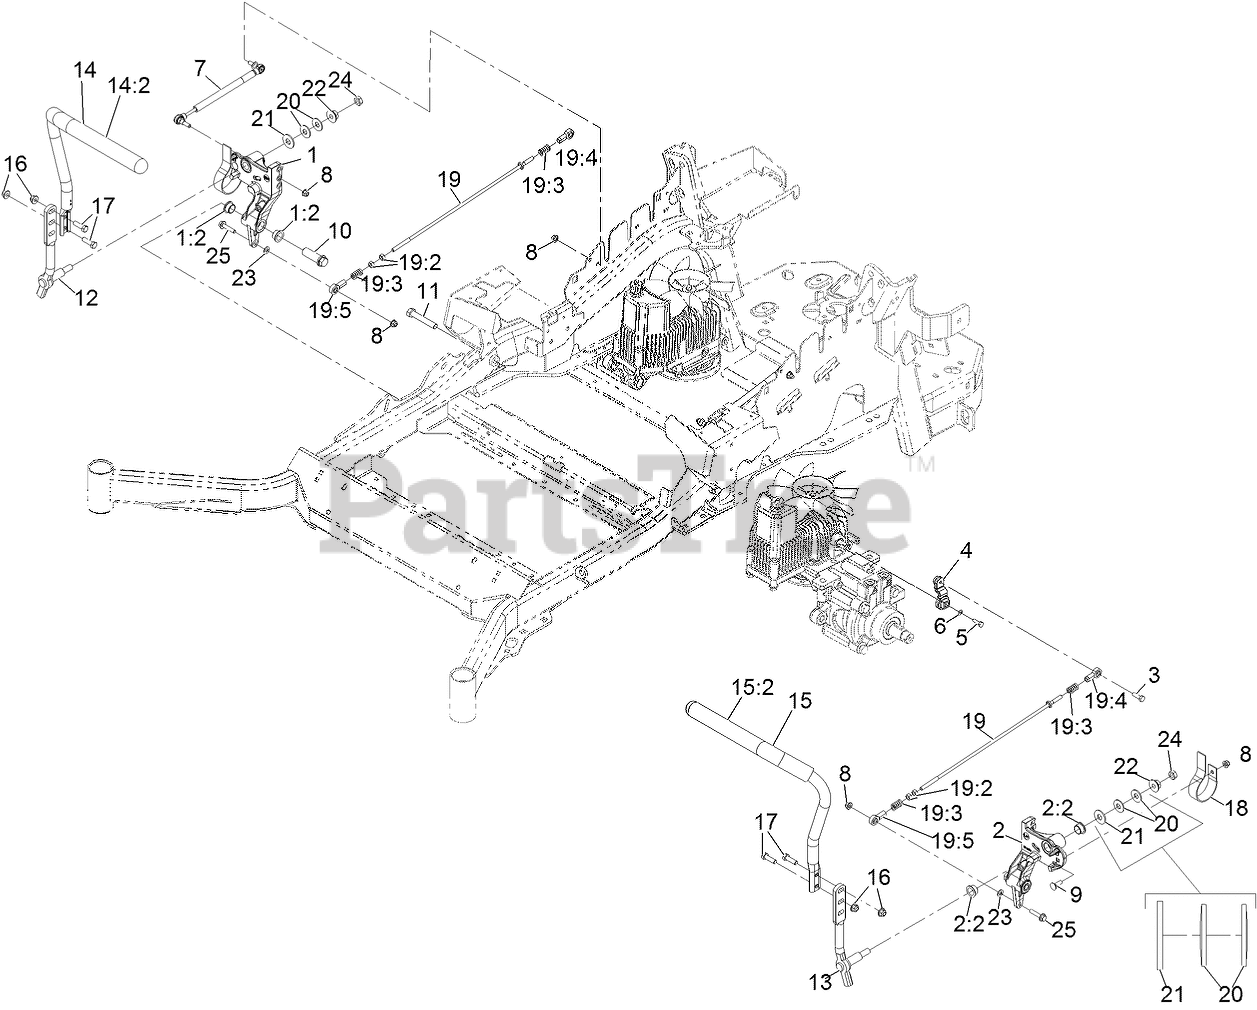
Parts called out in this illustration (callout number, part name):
1	RH MOTION CONTROL AND BUSHING ASM
1:2	BUSHING-FLANGE
2	LH MOTION CONTROL AND BUSHING ASM
2:2	BUSHING-FLANGE
3	SCREW-HH, THREAD LOCKING
4	ARM-CONTROL, PUMP
5	SCREW-HH
6	WASHER-SPRING
7	DAMPER-CONTROL, MOTION
8	NUT-HF, NI
9	BOLT-CARR
10	HUB-THREADED
11	SCREW-HH
12	LEVER-CONTROL MOTION, RH
13	LEVER-CONTROL MOTION, LH
14	HANDLE- RH W/GRIP
14:2	GRIP-LEVER, CONTROL
15	ASM-HANDLE-LH
15:2	GRIP-LEVER, CONTROL
16	NUT-HF, NI
17	SCREW-HH
18	SPRING-LEAF
19	FRONT PUMP LINKAGE ASM
19:2	NUT-HEX
19:3	SPRING-COMPRESSION
19:4	BALLJOINT-LH
19:5	BALLJOINT-RH
20	WASHER-SPRING
21	WASHER-FLAT
23	WASHER-PLAIN
24	NUT-JAM
25	SCREW-HHF
